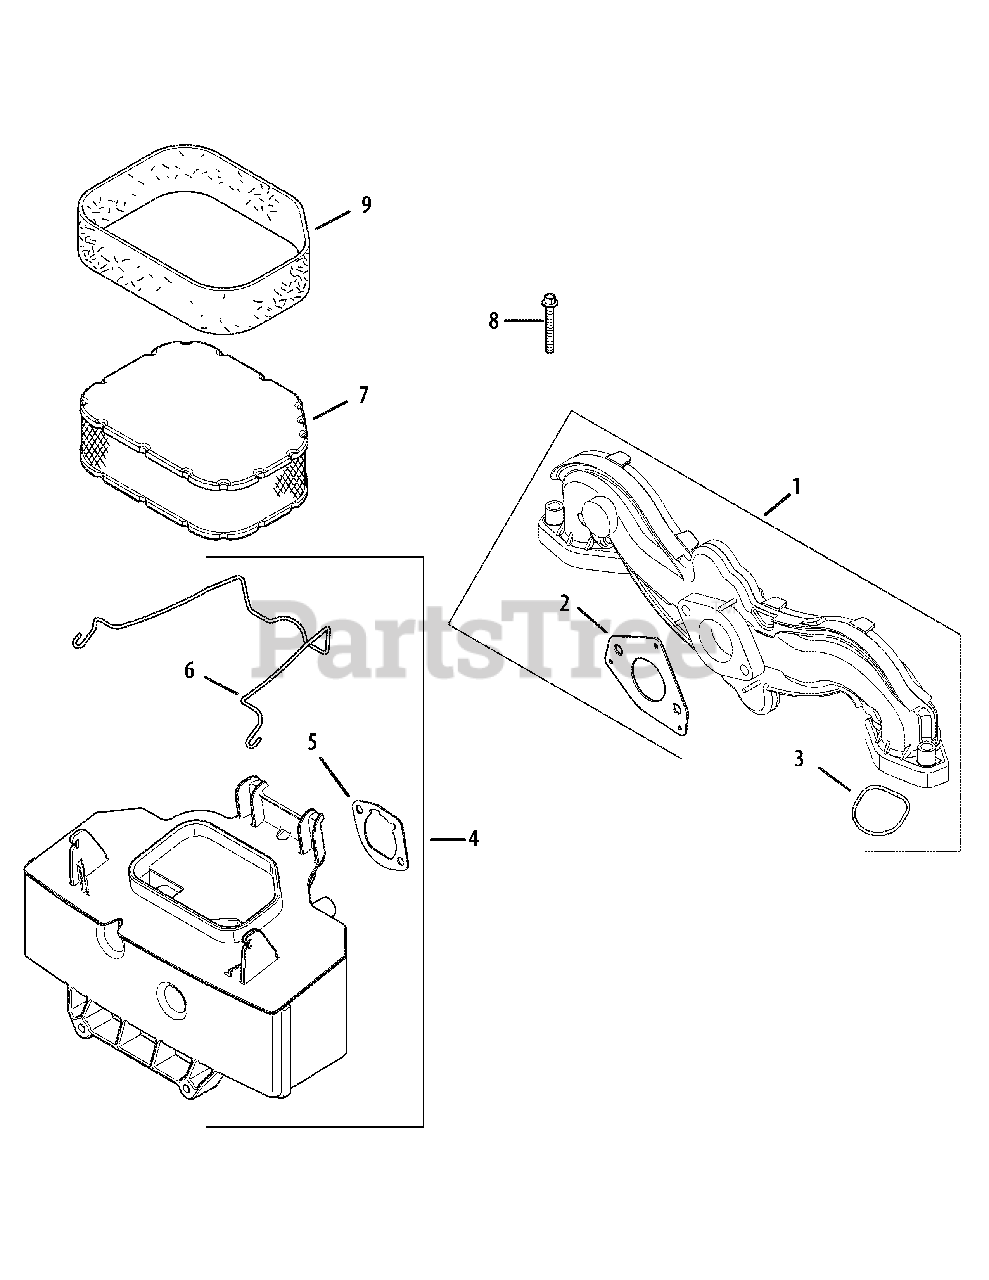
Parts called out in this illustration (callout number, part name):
1	Manifold, intake
2	Gasket, carburetor
3	O-Ring, intake port
4	Base, air cleaner
5	Gasket, air cleaner base
6	Latch, air cleaner element
7	Element, air cleaner
8	Screw, hex. flange M6x1.0x40
9	Pre-cleaner, element
